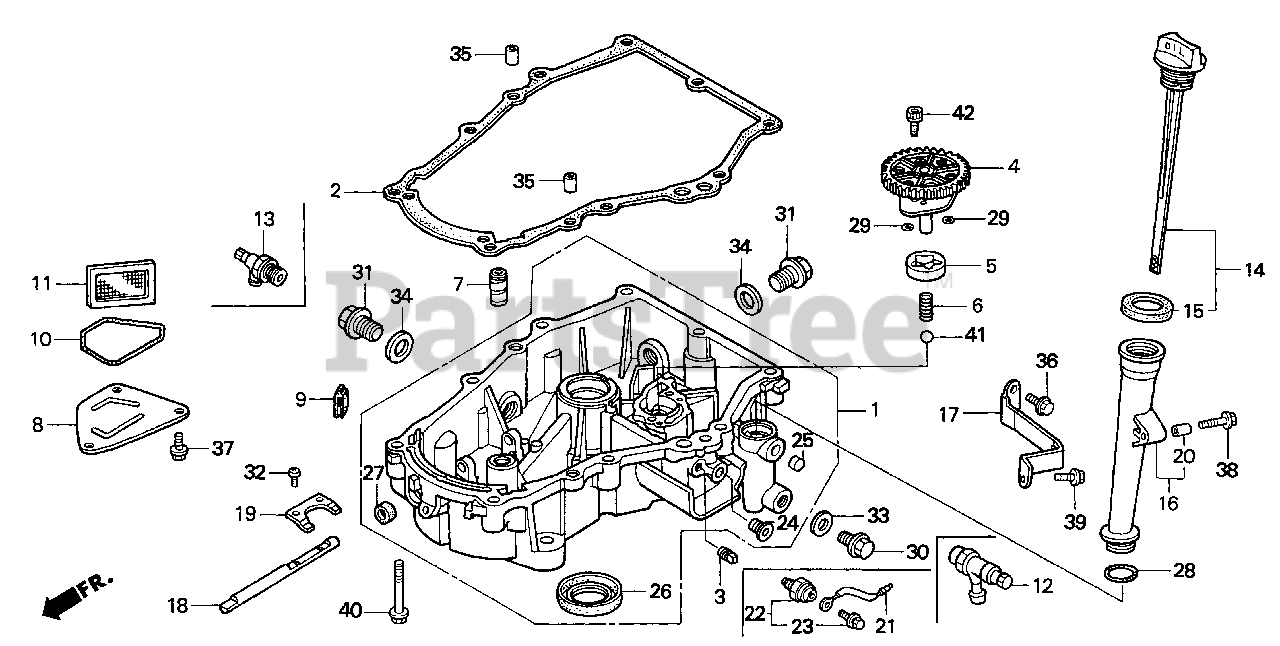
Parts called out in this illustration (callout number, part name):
1	PAN ASSY., OIL
2	GASKET, CASE COVER
4	COVER ASSY., OIL PUMP
5	ROTOR, OIL PUMP (OUTER)
6	SPRING, RELIEF VALVE
7	SHAFT, OIL CONTROL
8	PLATE, OIL FILTER
9	RUBBER, OIL RETURN
10	O-RING, OIL PLATE
11	SCREEN, OIL FILTER
12	VALVE, DRAIN (14X1.5)
13	VALVE, OIL SHUT-OFF
14	CAP ASSY., OIL FILLER
15	GASKET, OIL FILLER CAP
16	EXTENSION, OIL FILLER
17	STAY, OIL FILLER EXTENSION
18	SHAFT, GOVERNOR ARM
19	FORK, GOVERNOR
20	COLLAR, EXTENSION
21	WIRE, OIL PRESSURE SWITCH
22	SWITCH, OIL PRESSURE
23	SCREW-WASHER (4X8)
25	PLUG, SEALING (10MM)
26	OIL SEAL (38X58X11)
27	OIL SEAL (10X20X5)
28	O-RING (22.5X2.2)
29	O-RING (13X3.0)
30	BOLT, DRAIN PLUG (14MM)
31	BOLT, DRAIN PLUG (20MM)
32	SCREW, PAN (5X10)
33	WASHER, DRAIN PLUG (14MM)
34	WASHER, DRAIN PLUG (20MM)
35	PIN A, DOWEL (8X14)
36	BOLT, FLANGE (6X12)
37	BOLT, FLANGE (6X14)
38	BOLT, FLANGE (6X28)
39	BOLT, FLANGE (8X12)
40	BOLT, FLANGE (8X50)
41	BALL, STEEL (#12) (3/8)
42	BOLT, SOCKET (6X16)
